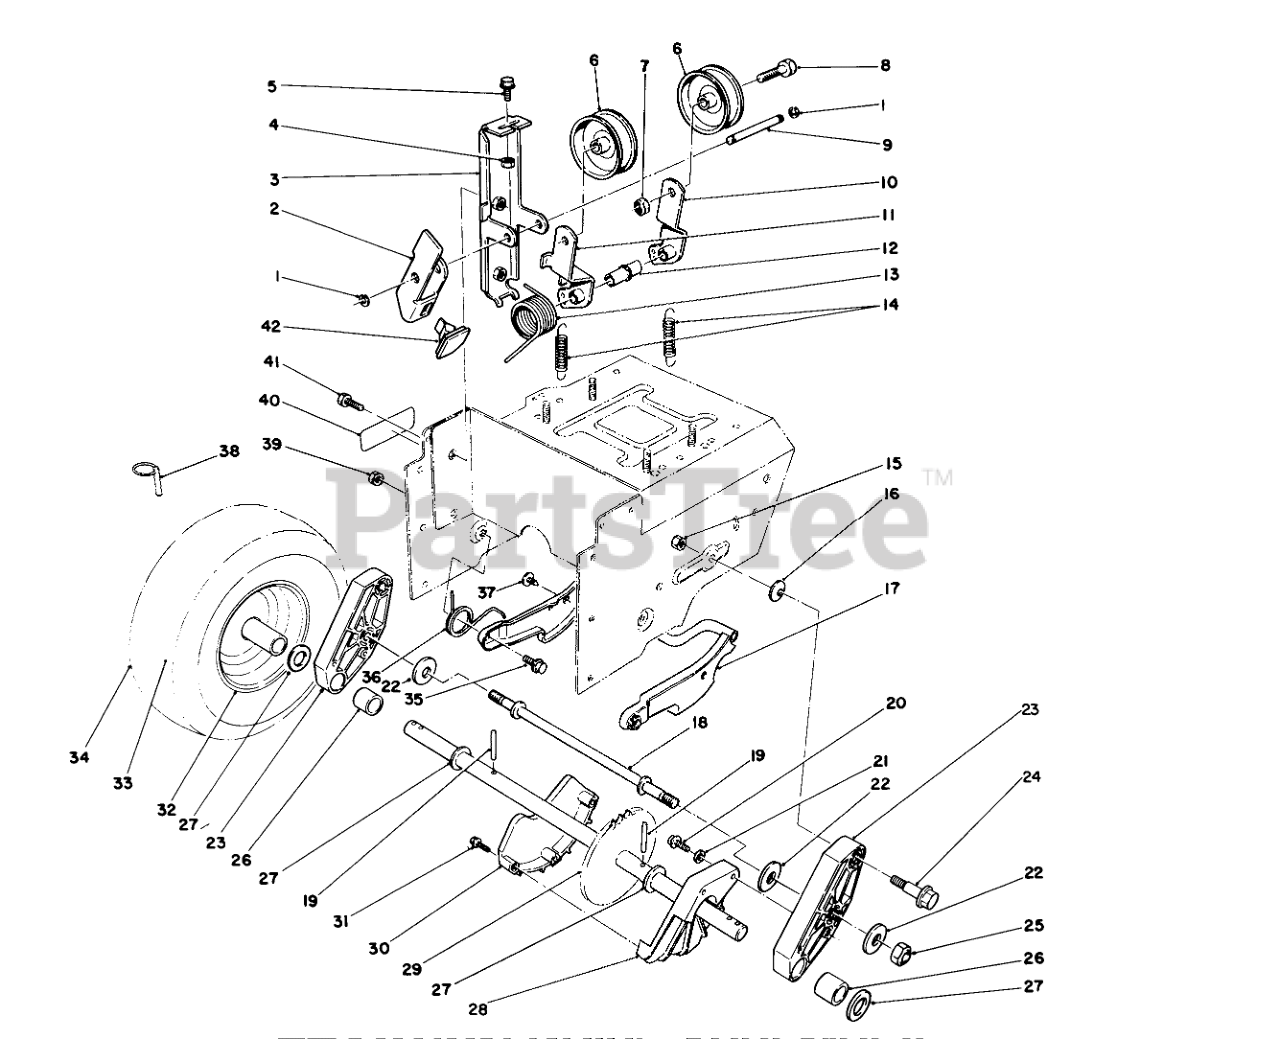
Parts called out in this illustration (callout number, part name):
1	RING-RETAINING
2	ARM-BRAKE
3	IDLER ARM BRACKET ASM
4	NUT-LOCK, NI
5	SCREW-HHF
6	PULLEY-IDLER
7	NUT-LOCK, NI
8	SCREW-HH
9	PIN-IDLER
10	ARM-IDLER, TRACTION
11	ARM-IDLER, IMPELLER
12	BUSHING-IDLER
13	TORSION SPRING
14	SPRING-EXTENSION
15	NUT-LOCK, NI
16	WASHER-SPRING
17	Latch-Arm
18	ROD-LATCH
19	PIN-ROLL, SLOTTED
20	SCREW-HWH
21	WASHER-FLAT
22	WASHER-SUPPORT
23	Pivot Arm Assembly (Incl. Ref.#26)
24	BOLT-SHOULDER
25	NUT-LOCK, NI
26	BUSHING-AXLE
27	WASHER-THRUST
28	GUARD-CHAIN, LH
30	GUARD-CHAIN, RH
31	SCREW-PPH
32	RIM-WHEEL
33	INNER TUBE
35	SCREW-SHOULDER
36	SPRING-LATCH, TORSION
37	FASTENER-PANEL
38	PIN-LYNCH
39	NUT-LOCK, NI
40	DECAL-WARNING
41	SCREW-HHF
42	PAD-BRAKE
